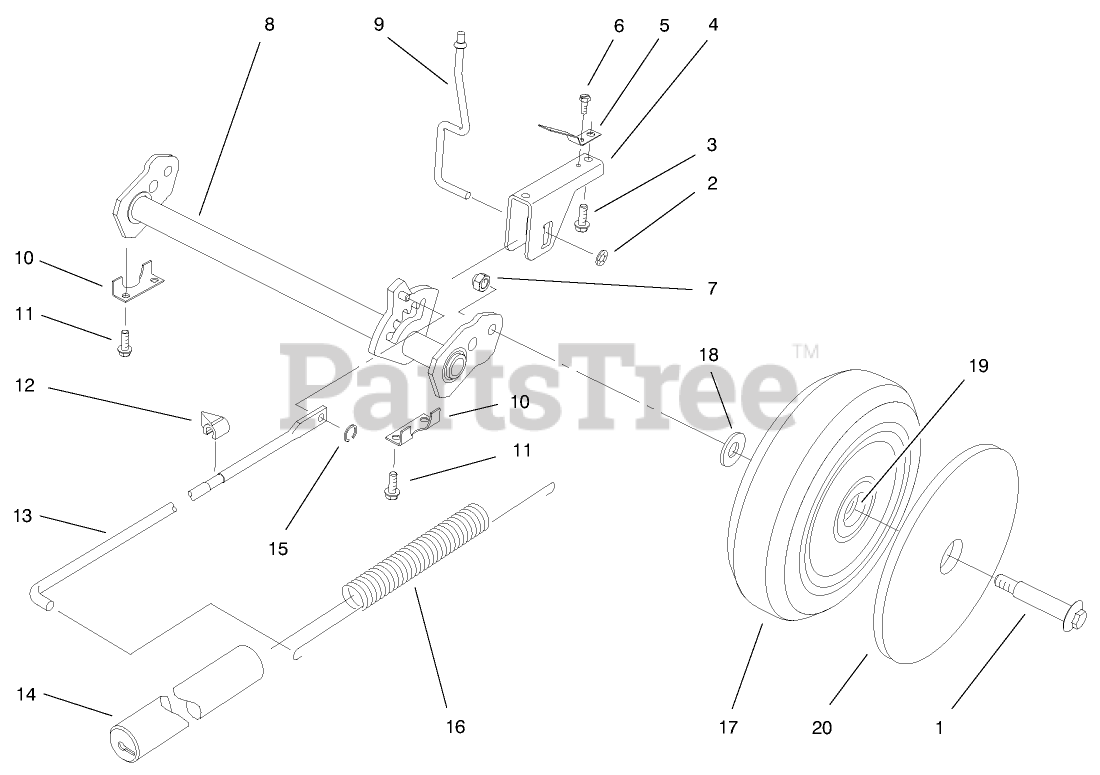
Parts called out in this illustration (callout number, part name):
1	BOLT-SHOULDER
2	PUSHNUT
3	SCREW
4	SADDLE - HOC
6	SCREW 8 - 32 X 250
7	LOCKNUT
8	PIVOT ARM REAR WA
9	TRIGGER ROD
11	SCREW-HWH
12	INDICATOR-HEIGHT OF CUT
13	LINK ROD
14	COVER-SPRING
15	GRIP RING
16	SPRING-COUNTERBALANCE
17	WHEEL ASM
18	WASHER
19	BUSHING
